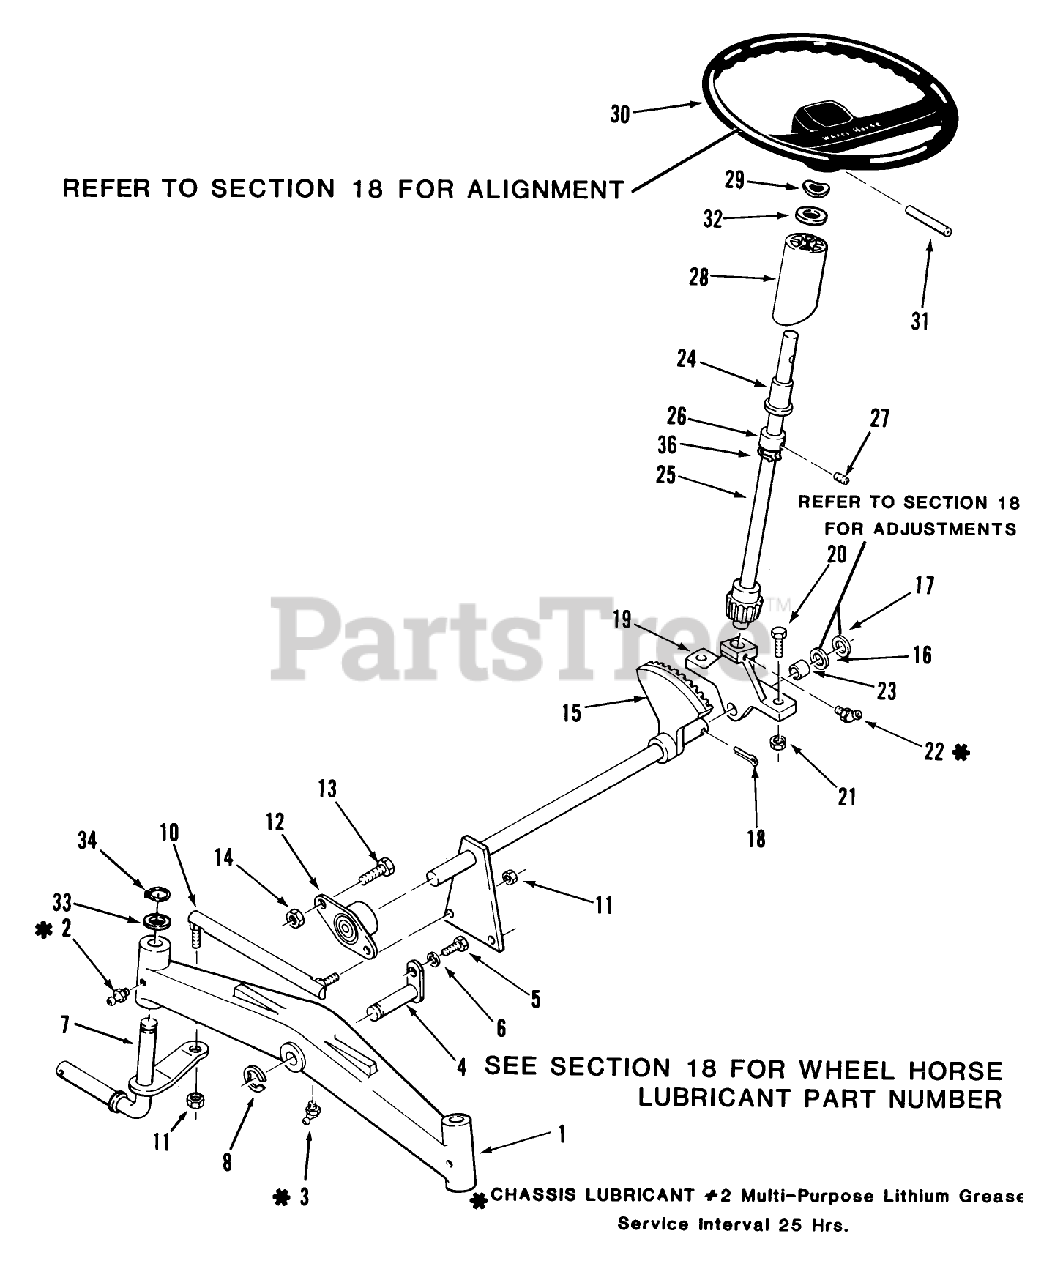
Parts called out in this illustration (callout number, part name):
3	FITTING-GREASE
4	PIN AND PLATE ASM
8	E-RING
12	BEARING-FLANGED
16	WASHER-SHIM
17	WASHER
23	BEARING-BRONZE
24	BEARING
34	WASHER
